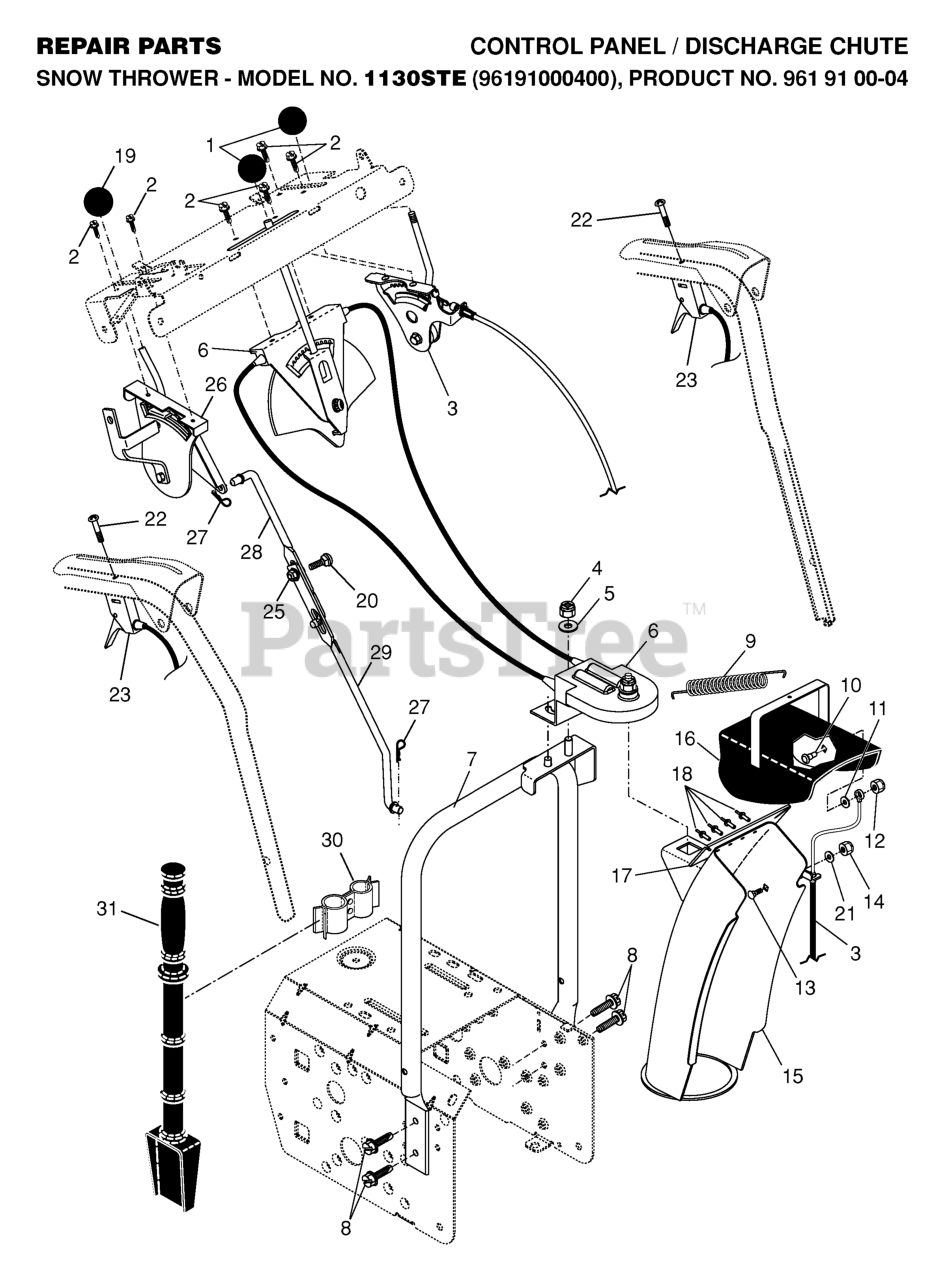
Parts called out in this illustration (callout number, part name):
1	KNOB, LEVER
2	SCREW #10-24 X 5/8
3	CONTROL ASSY, DEFLECTOR
4	NUT
5	WASHER
6	CONTROL ASSY, CHUTE ROTATER
7	SUPPORT CHUTE ROTATER
8	SELF-TAPPING SCREW 5/16-18X3/4
9	SPRING.DEFLECTOR.REM.CHUTE
10	BOLT, SHOULDER
11	WASHER, NYLON FRICTION
12	LOCKNUT.NYLOC.1/4-20
13	BOLT
14	NUT.71038.31-18.HEX.NYLOCK
15	CHUTE ASSY
16	DEFLECTOR.WELDMENT.PNT.ORANGE
17	SEAL, DEFLECTOR
18	RIVET BLIND
19	RP KNOB, SPEED CONTROL LEVER
20	BOLT
21	WASHER.20X8.5
23	STEERING.CONTROL.SNOW.BLUE
25	NUT.FLANGE.5/16
26	HEAD ASSY SPEED
27	SPRING RETAINER
28	ROD, UPPER SPEED CONTROL
29	ROD, LOWER SPEED CONTROL.SNOW
30	CLAMP.ASM.CLEANOUT.TOOL.SNOW
31	CLEAN OUT TOOL
